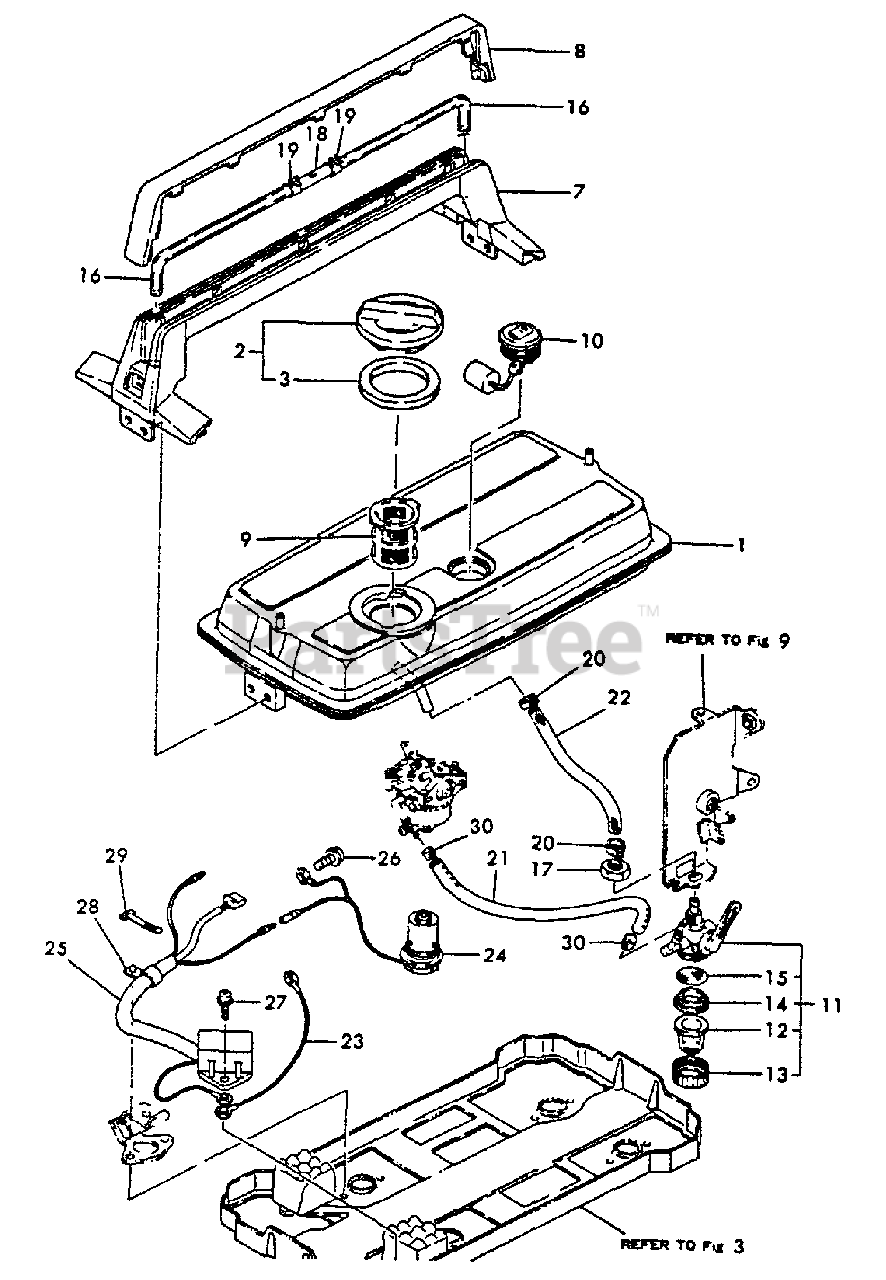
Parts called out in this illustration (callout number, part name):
1	FUEL TANK ASSY
2	CAP ASSY, FUEL TANK
3	GASKET, CAP
7	GRIP ASSY, FUEL TANK
8	CAP, GRIP
9	FILTER, FUEL
10	GAUGE, FUEL
11	COCK ASSY, FUEL
12	BOWL, STRAINER
13	RETAINER
14	GASKET
15	FILTER, FUEL
16	HOSE
17	LOCKNUT - 12 -- PLATED
18	JOINT
19	CLAMP, HOSE - 10
20	CLAMP, HOSE
21	PIPE, FUEL
22	PIPE, FUEL
23	WIRE A
24	SENSOR, OIL LEVEL
25	UNIT, OIL SENSOR
26	SCREW - 6×12
27	SCREW - 6×12
28	CLAMP
29	CLAMP
30	CLAMP, HOSE - 10
